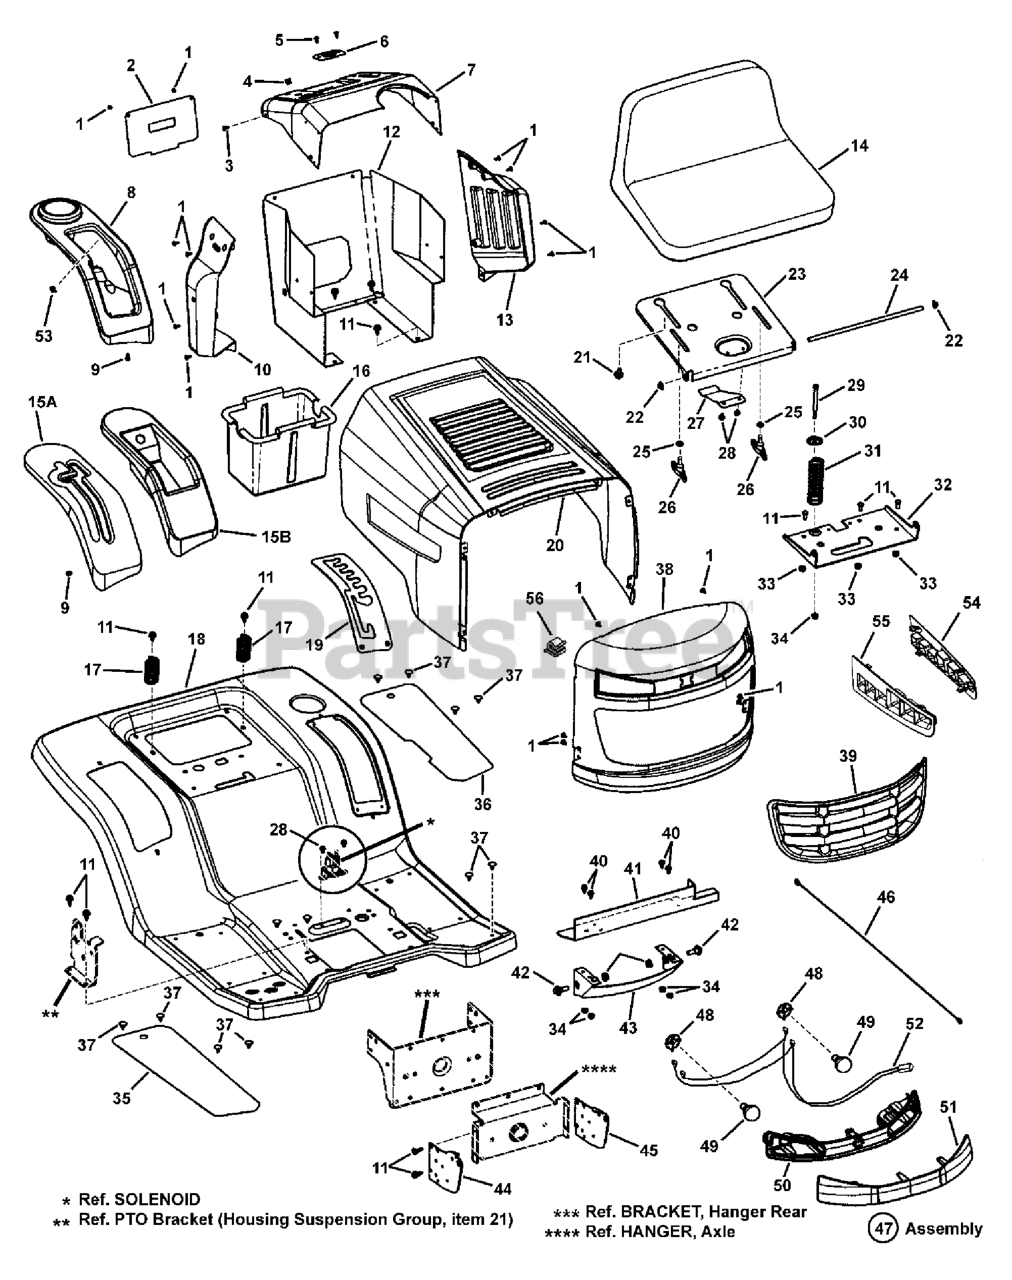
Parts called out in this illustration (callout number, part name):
1	SCREW, THREAD FORMING 10-24X.340MIN THREADS
2	PANEL, ACCESS
3	SCREW, 0.375 X #8 SELF TAP Z/BL CHROMATE
4	BUSHING - INSULATING
5	SCREW 1/4" ABX.50
6	BEARING, STEERING
7	DASH-TWIN
8	POD W/ CUP HOLDER
9	1/4-20 THREAD CUTTING SCR
10	PANEL, RIGHT SIDE
11	CAPSCREW 5/16-18
12	SUPPORT, DASH
13	PANEL, LEFT SIDE
14	SEAT, LOW BACK
15A	POD W/ DRIVE
15B	POD W/ COMPARTMENT
16	CONTAINER, BATTERY
17	SPRING, COMPRESSION 2.43LENGTH
18	SEAT DECK
19	PLATE, INDEX
20	HOOD, WM2
21	BOLT, SHOULDER 5/16-18
22	CAP, PUSH ON
23	SUPPORT, SEAT
24	ROD, PIVOT
25	FW, .34X.62X16GA
26	BOLT - WING, 0.62L X 5/16-18 UNC 2A
27	SPRING - LEAF
28	SCREW 1/4-14X.38"ST-
29	BOLT, SHOULDER 1/4-20 X 3.652 2A
30	HER - CUP, 1.50 OD X 0.344 ID
31	SPRING, COMPRESSION 4.57 FREE LENGTH
32	BRACKET, SEAT PIVOT
33	NUT, Nylock 5/16-18
34	1/4-20 HFN
35	MAT, RH
36	MAT, LH
37	FASTENER PANEL
38	HOOD, GRILLE
39	LOUVER, INSERT
40	HHCS, 1/4-20 x 5/8
41	BRACKET, SUPPORT
42	SHOULDER BOLT, 3/8-16X1.06
43	BRACKET, LOWER PIVOT
44	SUPPORT - GRILLE, RIGHT
45	SUPPORT - GRILLE, LEFT
47	ASSY, HEADLIGHT, TCT, MURRAY
48	SOCKET, LIGHT
49	BULB, 12.8V
50	HOUSING, LIGHT
51	LENS, LIGHT
52	HARNESS-HEADLIGHT
53	CUTTING HEIGHT INDICATOR
54	INSERT, WM2 HOOD, LEFT
55	INSERT, RIGHT HOOD, WM2
56	RETAINERS, S-Clips
